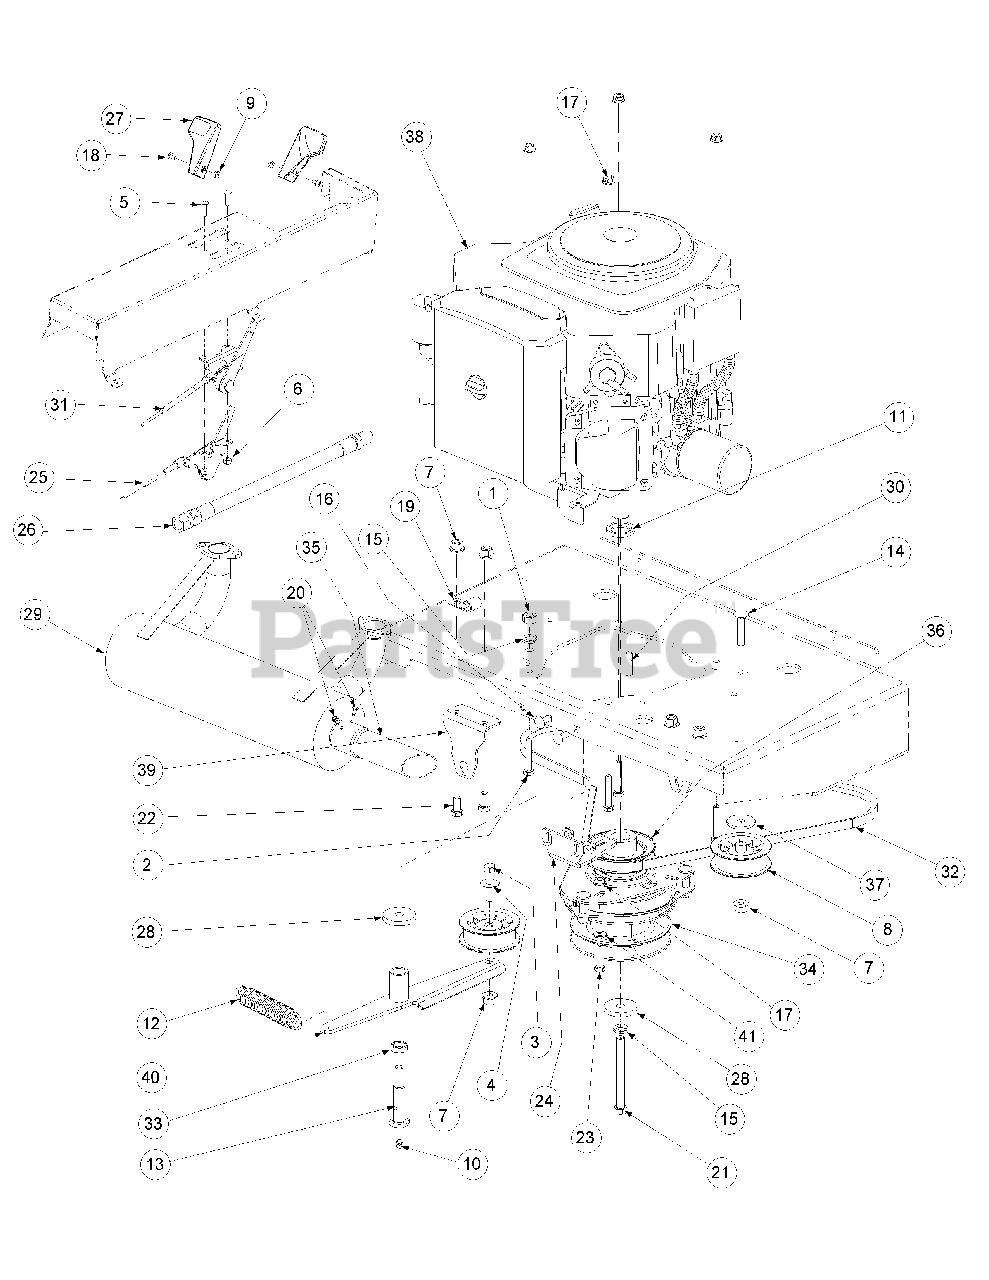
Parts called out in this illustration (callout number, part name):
1	Hex Nut, 7/16-14
2	HHCS, 5/16-18, 1-3/4
3	Capscrew, 3/8-16 x 1-3/4
5	Round Hd. Machine Screw, 10-32 x 3/4
6	Lock Nut, Nylon Insert, 10-32
7	Flange Lock, Hex Nut, 3/8-16
8	Idler Pulley w/ Adaptor
9	Nut Washer, W/Star, 8-32
10	Grease Fitting, 1/4-28 x 3/16
11	Engine Spacer
12	Extension Spring, 1.0 OD x 5.00
13	Shoulder Screw, 7/16-14
14	Hex Carriage Screw, 3/8-16, 1.75
15	Lock Washer, 7/16
16	Carriage Bolt:5/16-18 x 3/4
17	Hexflange Lock Nut, 5/16-18
18	Machine Screw, 8-32, .375
19	Clip, Heat Shield Cable
20	Tube Clamp, 1.375
21	HHCS, 7/16-20 x 4.00
22	Hex Cap Screw, 3/8-16, .750
23	Hex Cap Screw:5/16-18 x 1-1/4
24	Retainer Clutch Assembly, Ogura
25	Throttle, Control Cable, 45.0
26	Oil Drain Hose
27	Control Throttle Knob
28	Flat Washer, 7/16 IDx 1.750 OD x .250T
29	23HP Kohler Exhaust
30	Key, 1/4 x 1/4 x 1.25
31	Choke, Control Cable, 38.0
32	V-Belt, 56.00
33	Spacer, .635 ID x .28
34	Electric Clutch OGURA
35	Muffler Accessory Exhaust Tube
36	Transmission Drive Pulley
37	Washer, 5/16-18
38	23HP Kohler Engine
39	Neutral Lock Mounting Bracket
40	Engine Idler Arm Assembly Includes:
41	Flat Washer, 5/16
